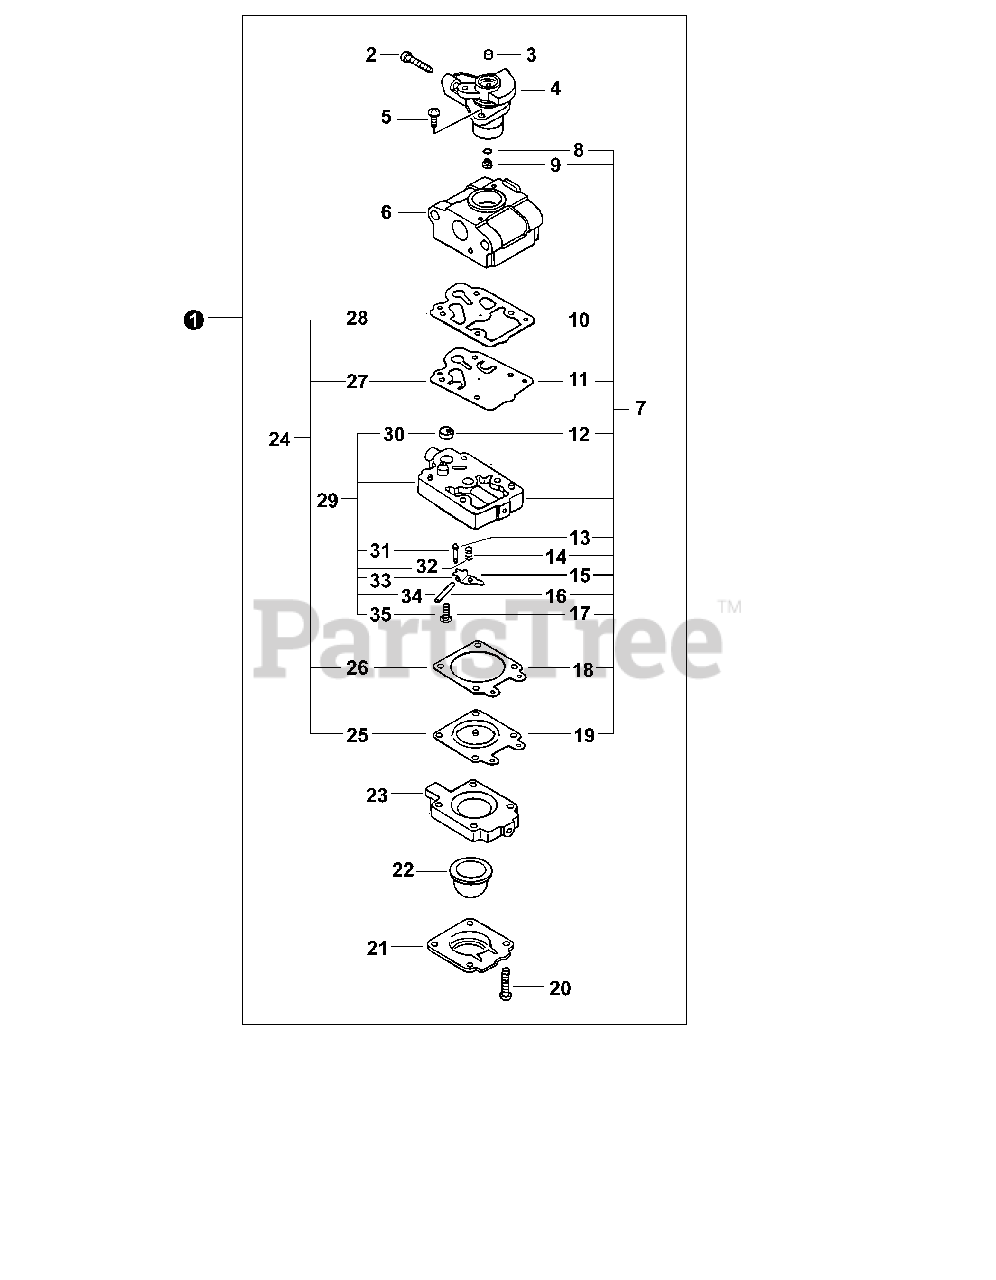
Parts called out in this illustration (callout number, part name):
1	CARBURETOR WYL-180A
2	SCREW, IDLE ADJUST
3	CAP, LIMITER
4	THROTTLE VALVE ASSY
6	BODY, CARBURETOR
7	REPAIR KIT
8	O-RING
9	JET
10	GASKET, PUMP
11	DIAPHRAGM, PUMP
12	STRAINER
13	VALVE, INLET NEEDLE
14	SPRING, METERING LEVER
15	LEVER, METERING
16	PIN, METERING LEVER
17	SCREW, METERING LEVER PIN
18	GASKET, DIAPHRAGM
19	DIAPHRAGM, METERING
20	SCREW, PUMP COVER
21	RETAINER, PURGE BULB
22	BULB, PURGE
23	PURGE BASE ASSY
24	GASKET/DIAPHRAGM KIT
25	DIAPHRAGM, METERING
26	GASKET, DIAPHRAGM
27	DIAPHRAGM, PUMP
28	GASKET, PUMP
29	BASE, PURGE
30	STRAINER
31	VALVE, INLET NEEDLE
32	SPRING, METERING LEVER
33	LEVER, METERING
34	PIN, METERING LEVER
35	SCREW, METERING LEVER PIN
